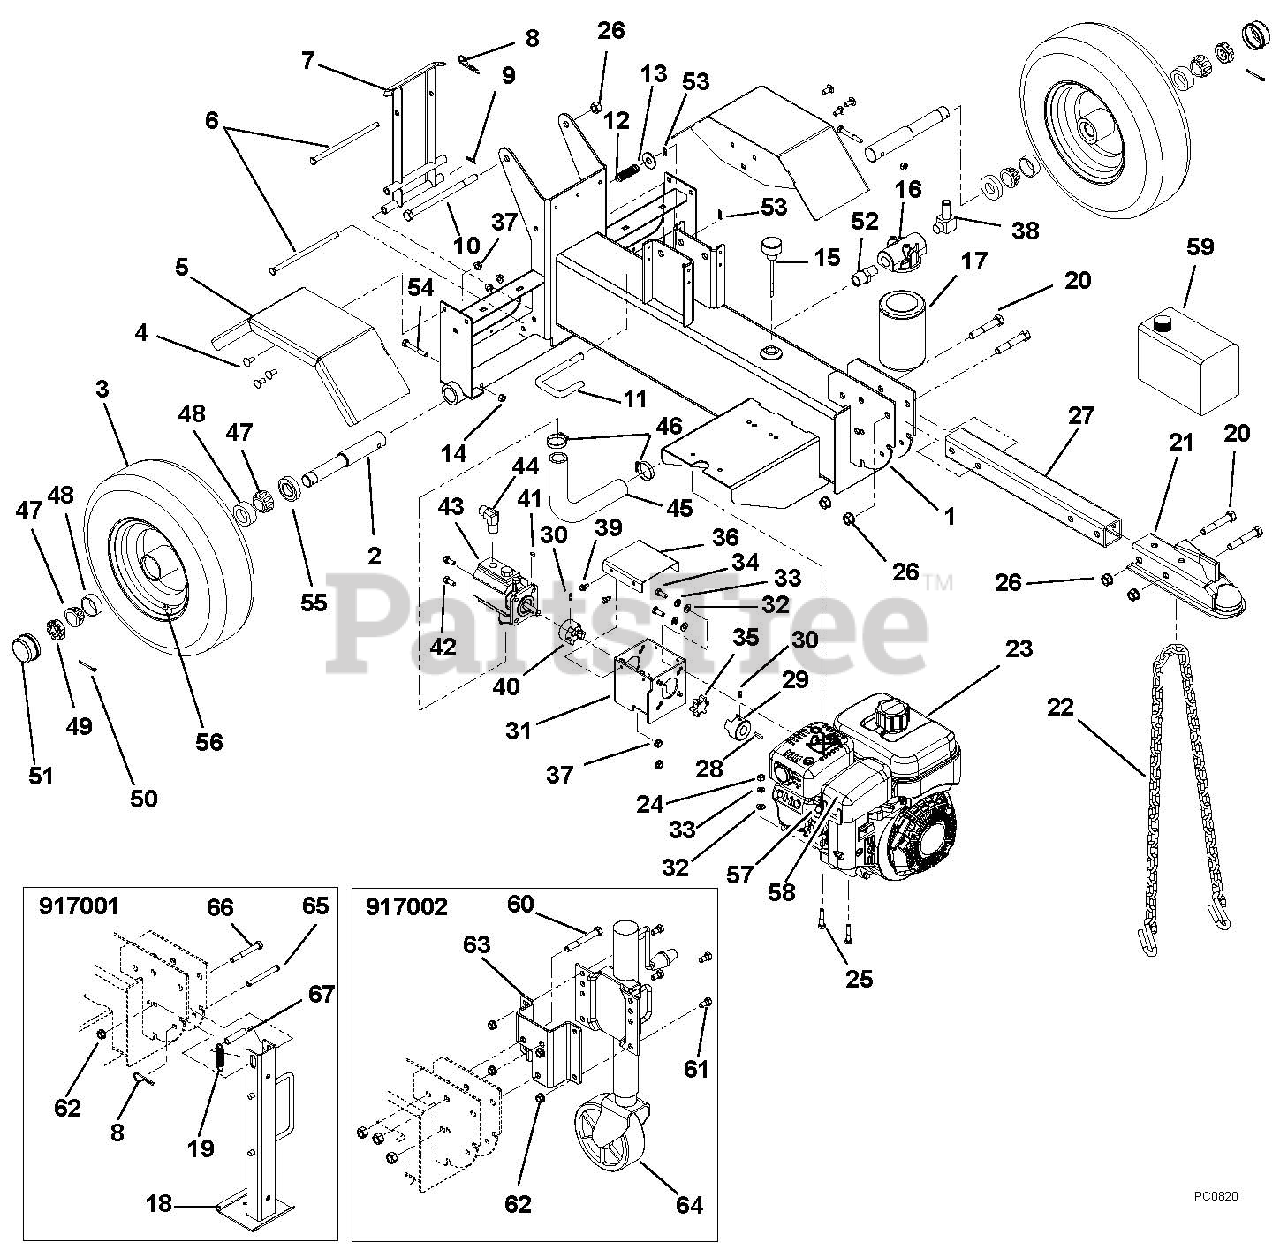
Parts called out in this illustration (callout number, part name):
1	CHASSIS,SPLITTER W/SAFTY DECAL
2	AXLE, SPLITTER
3	WHEEL, SPLITTER
4	@BLT-RDHDSQNK .31-18X.75 G5YZ
5	WLDMT, FENDER
6	PIN, LOCK
7	REAR STAND W/DECALS (ARIENS)
8	HAIRPIN, #7 CLIP .094X2.31 YWZ
9	PIN-HAIR, ENDRIES #25 YWZC
10	@BLT-HEX .50-13X7.50 GR5 YWZC
11	LOCK, BEAM
12	SPRG, COMP .058X.65X2.13 WLD15
13	@WSHR-FL-STL.563X1.38X.109YWZC
14	@NUT-LK-CTR .31-18 YWZC
15	BREATHER, DIPSTICK
16	HEAD, FILTER - 3/4 NPT
17	FILTER,OIL-W/BYPASS
18	WLDMT, JACK STAND
19	SPRG, TENSION .063X.625X2.50
20	@BLT-HEX .50-13X3.00 GR5 YWZC
21	HITCH, BALL-2"
22	CHAIN, SAFETY
23	ENGINE,SUBARU 6HP SP170 (CARB)
23	ENGINE,SUBARU EX21 (CARB)
24	@NUT-HEX .31-18 YWZC
25	@BLT-HEX .31-18X1.50 GR5 YWZC
26	@NUT-LK-CTR .50-13 YWZC
27	HITCH BAR W/DECALS
28	KEY-SQ .188X.75X.188
29	HUB,DRIVE COUPLING 3/4"
30	SCR-SET .25-20X.38 SKHCUPNL OH
31	WLDMT, PUMP MOUNT BRKT
32	@WSHR-FL-STL.344X.688X.065YWZC
33	WSHR-LK .312X.097 HVY YWZC
34	BLT-HEX .31-24X.75 YWZC GR5
35	SPIDER,URETHANE
36	COVER W/DECALS
37	@NUT-LK-TOP-FLG .31-18 YWZC
38	FTG,HYD 4501-10-12-FG
39	SCR-TAP .25-20X.50 HWH TR YWZ
40	HUB,DRIVE COUPLING 1/2"
41	KEY-WDRF .125X.50X.20 (HRDEND)
42	@BLT-HEX .31-18X.75 GR5 YWZC
43	PUMP, SPLITTER-11 GPM
43	PUMP,SPLITTER-13 GPM
44	FTG,HYD 2501-8-8
44	FTG,HYD 6801-8-8
45	HOSE,HYD SUCTION 16G4H X 13.5
46	CLAMP-HOSE 1.50X.81X1.42
47	BRG, CONE W/ GREASE
48	BRG-CUP1.980X.420
49	NUT-SL 1.0-14
50	@PIN-CTR .15X1.50 YWZC
51	CAP,DUST
52	FTG,HYD 5404-12-12
53	CLIP, SPRING
54	@BLT-HEX .31-18X2.25 GR5 YWZC
56	VALVE STEM ASS'Y
57	SPARK PLUG,SP-170
58	FILTER,SP-170 SPONGE/ROBIN
59	OIL, 2.5 GAL HYD ISO GRADE 32
60	@BLT-HEX .50-13X3.25 GR5 YWZC
61	@BLT-HEX .38-16X.75 GR5 YWZC
62	@NUT-LK-TOP-FLG .38-16 YWZC
63	BRACKET, MOUNTING
64	STAND, JACK-W/WHEEL
65	PIN-CLEV .371X3.25 YWZC
66	@BLT-HEX .38-16X3.00 GR5 YWZC
67	SPCR, WHEEL .385X.500X2.00
